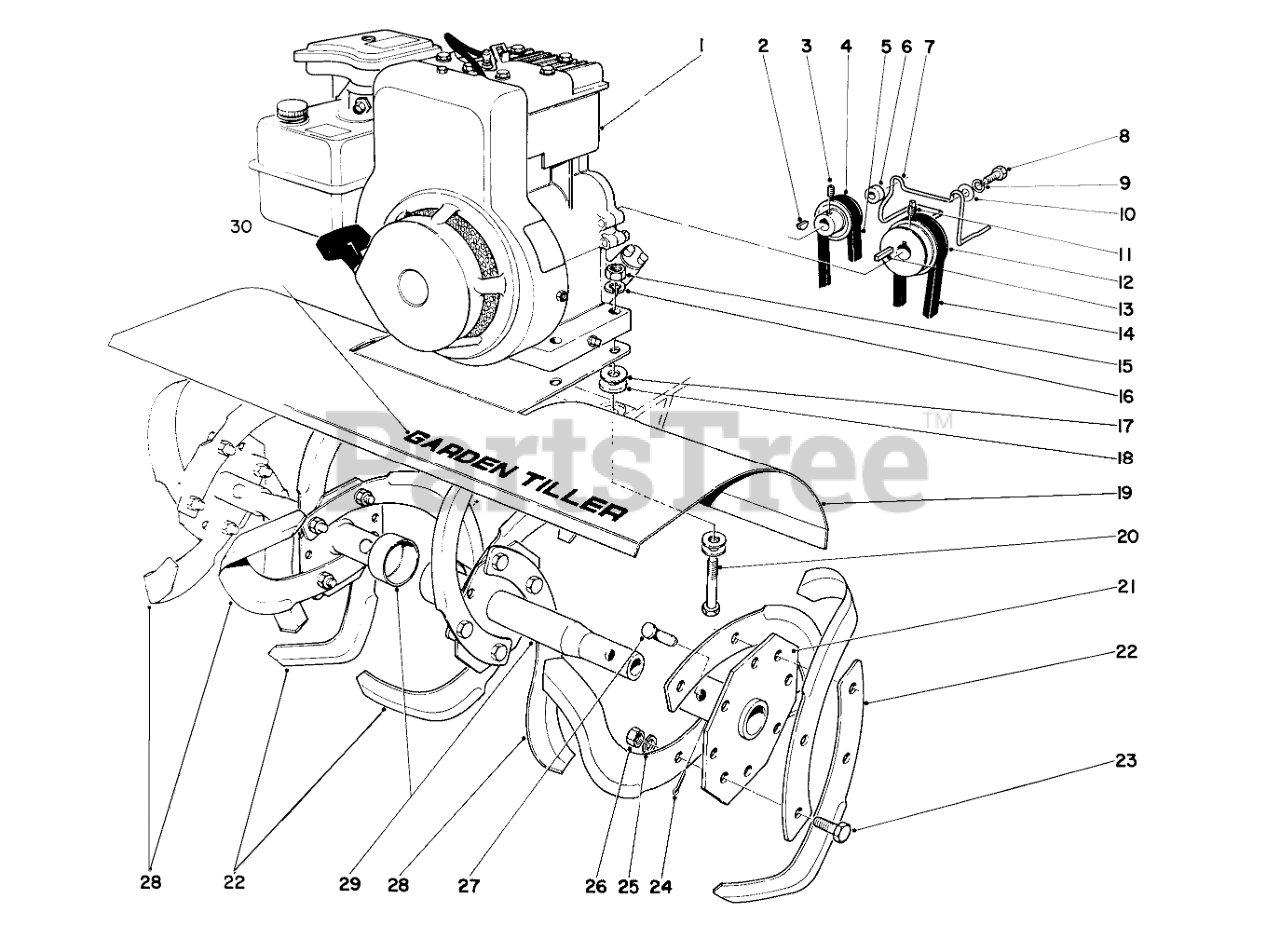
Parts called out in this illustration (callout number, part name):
1	Engine
2	KEY-WOODRUFF
3	SCREW-SET
4	Pulley
5	V-BELT
6	SPACER
7	BELT GUIDE
8	SCREW-HH
9	WASHER-LOCK
10	WASHER-FLAT
11	SCREW-SET, HSH
12	Engine Pulley
13	KEY-SQUARE
14	Belt
15	NUT-HEX
16	WASHER-LOCK
17	WASHER-FLAT
18	WASHER-FLAT
19	Shield
20	SCREW-HH
21	Axle Hub
22	RH TINE
23	SCREW-HH
24	PIN-COTTER
25	WASHER-LOCK
26	NUT-HEX
27	PIN-CLEVIS
28	LH TINE
29	Axle Hub
30	Decal
